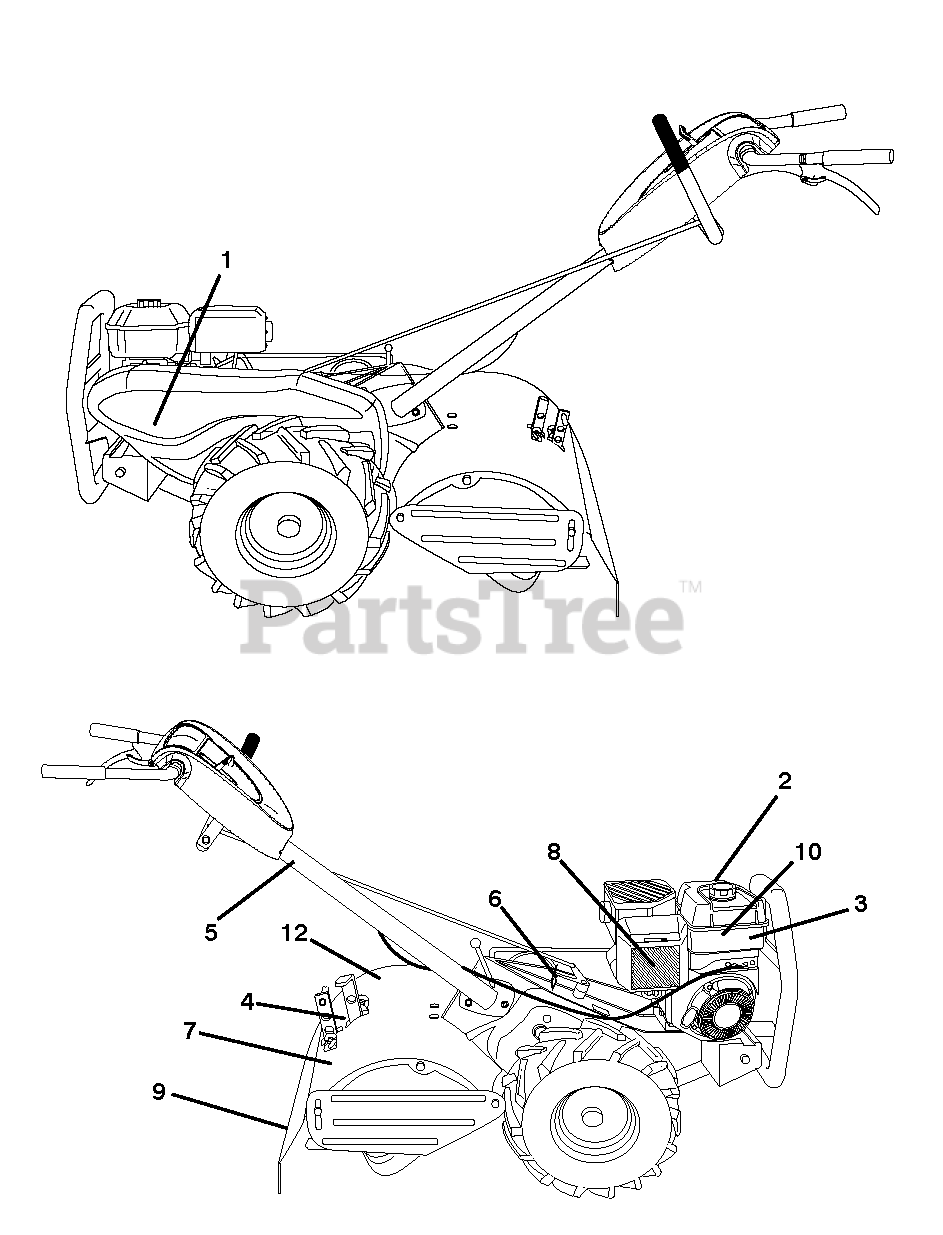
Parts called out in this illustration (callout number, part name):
1	RP.DECAL.BADGE.170MM.TEXTLOGO
2	DECAL,ETHANOL E85 WARNING
3	DECAL, WARNING SPARK ARRESTOR
4	DECAL.SHIELD.TN.DRT17.HUSQ
5	DECAL TI (2 2)
6	DECAL.SHIFT.INDICATOR.DRT
7	DECAL.REVERSE.HUSQ.TILLER
8	DECAL.B&S.900.A/S.C (279005)
9	DECAL.DRT.WARN.ENG/F
10	DECAL.B&S.900.TANK.REF.276991
12	DECAL.FOWARD.HUSQ.TILLER
